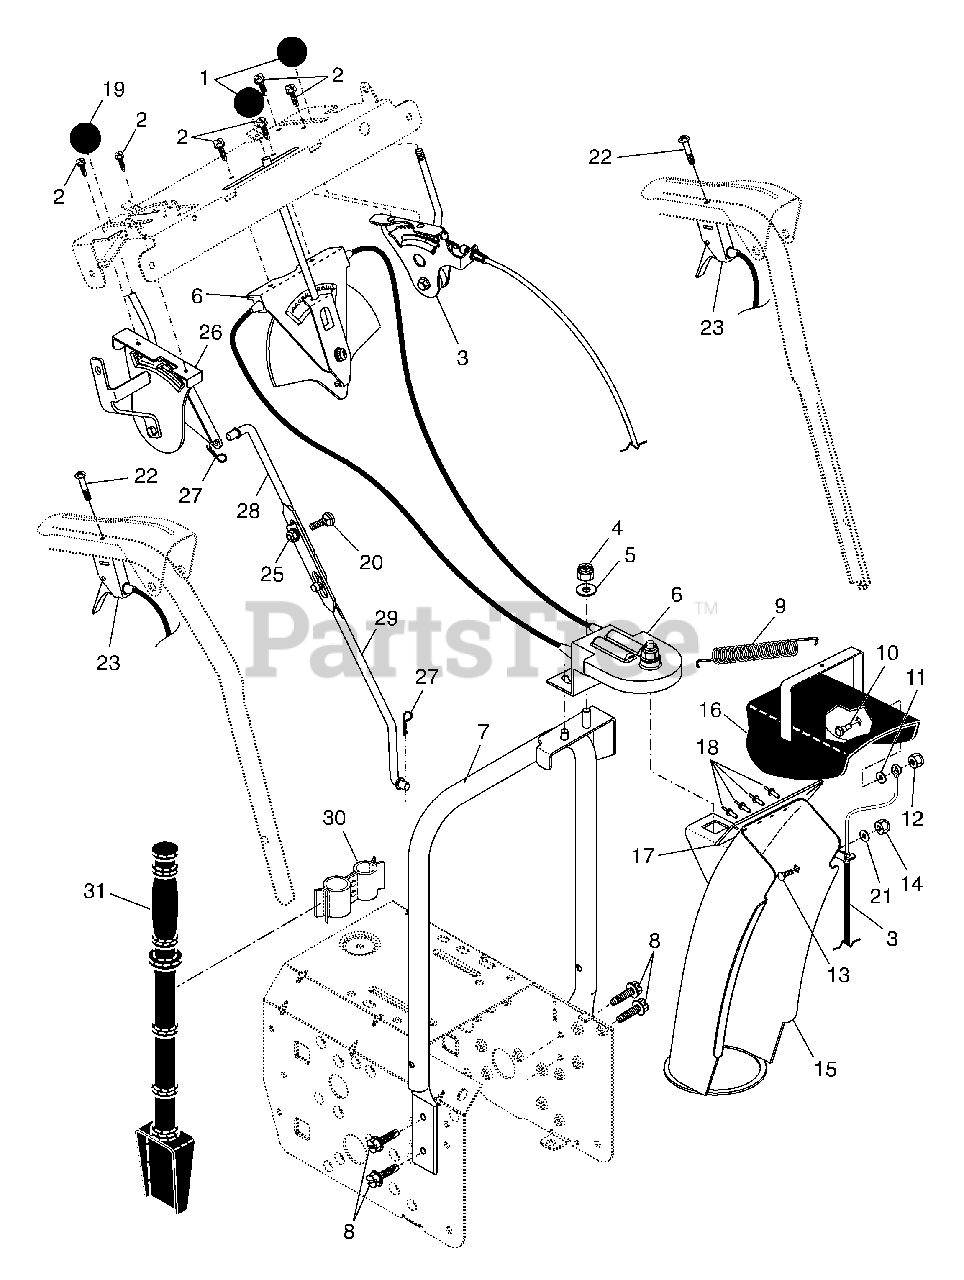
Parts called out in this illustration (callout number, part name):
1	Knob, Lever
2	Screw #10-24 x 5/8
3	Control Assembly, Deflector
4	Nut, Lock 3/8-16
5	Washer, Flat 3/8
6	Control Assembly, Chute Rotater
7	Support, Pivot
8	Screw, Hex Head 5/16-18 x 3/4
9	Spring, Deflector
10	Bolt, Shoulder
11	Washer, Flat 1/4
12	Nut, Lock 1/4-20
13	Bolt, Carriage 5/16-18
14	Nut, Lock 5/16-18
15	Chute Assembly
16	Deflector Assembly
17	Seal, Deflector
18	Rivet, Blind
19	Knob, Speed Control Lever
20	Bolt, Carriage 5/16-18 x 3/4
21	Washer, Flat 5/16
22	Screw #10-24 x 1-1/2
23	Control Assembly, Power Steering
25	Nut, Lock 5/16-18
26	Lever Assembly, Speed Control
27	Retainer, Hairpin
28	Rod, Upper, Speed Control
29	Rod, Lower, Speed Control
30	Clamp, Clean-Out Tool
31	Tool, Clean-Out
